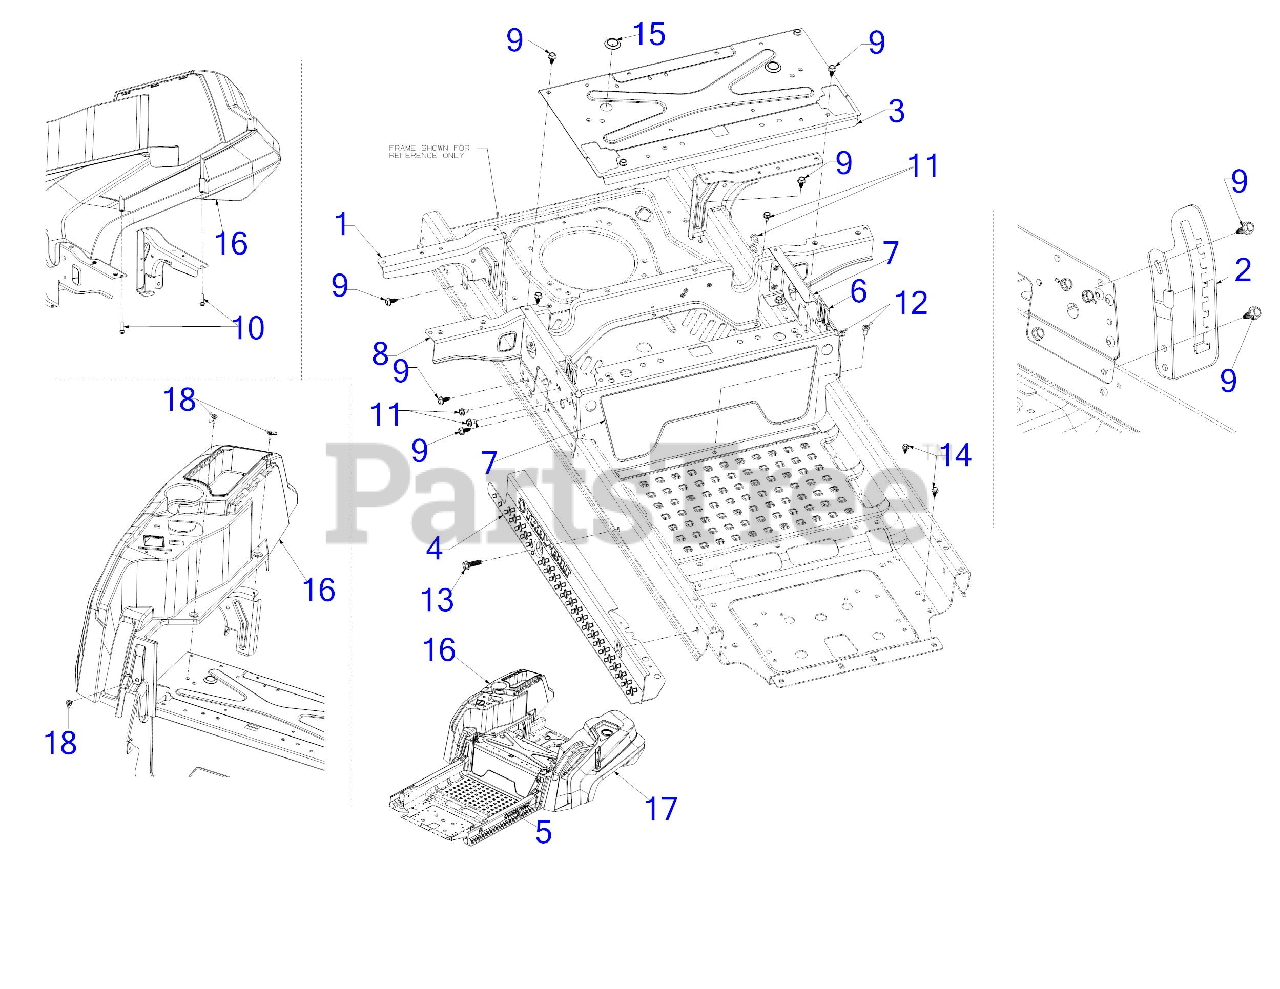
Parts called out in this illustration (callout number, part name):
2	HEIGHT INDEX BRACKET
9	SCREW 5/16-18 x .750
10	SCREW 5/16-14 x 1
11	SCREW 5/16-18 x .500
12	SCREW 5/16-18 X.75
13	SCREW 3/8-16 X1.250
14	SCREW 1/4-20X.625
16	CONSOLE (RH)
17	CONSOLE (LH)
18	SHOULDER SCREW M6-1 .368 X.115
